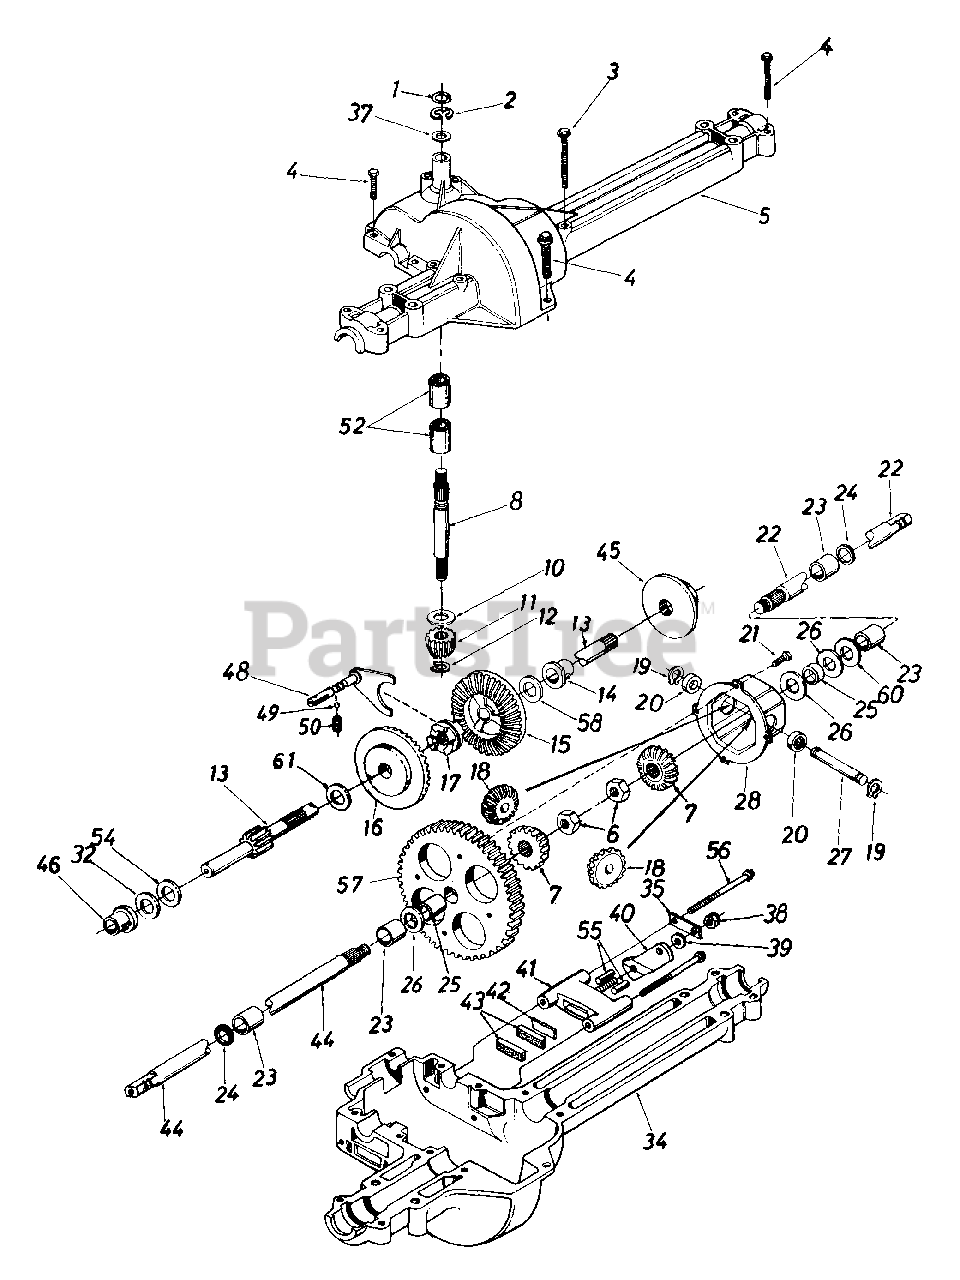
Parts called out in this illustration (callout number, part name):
3	Hex Wash. TT-Tap Scr. 1/4-20 x 1.75" Lg.
4	Hex Tap Scr. 1/4-20 x 1.25" Lg.
5	Upper Housing
6	Hex Jam Nut 1/2-20 Thd.
7	Miter Gear
10	Thrust Washer 5/8" I.D. x 1.25" O.D.
11	Pinion Input 14T
12	Retaining Ring
13	Drive Shaft - R.H. Brake
14	Flange Brg. 5/8" I.D. x 3/4" Lg.
15	Bevel Gear 42T Small I.D.
16	Bevel Gear 42T Large I.D.
17	Clutch Collar
18	Miter Gear 15T (H.D.)
19	Snap Ring
20	Thrust Bearing
21	Pan Head Scr. 1/4-20 x .50" Lg. w/Patch
23	Sleeve Bearing 3/4" I.D. x 1.0" Lg.
24	Oil Seal 3/4" I.D.
26	Fl-Wash..760" I.D. x 1.5" O.D.
28	Differential Can Ass'y.
32	Washer
34	Lower Housing
35	Anti-Rotation Brkt.
37	Washer
38	Hex Nut 5/16-24 Thd.
39	Fl-Wash..344" I.D. x .875" O.D.
40	Actuating Arm
41	Brake Yoke
42	Puck Plate
43	Brake Puck
46	Flange Bearing 5/8" I.D. x 15/16" Lg.
48	Shift Fork Ass'y.
49	Ball Detent .250" Dia.
50	Spring Detent
52	Needle Brg. 5/8" I.D. x 1/2" Lg.
54	Fl-Wash. 5/8" I.D. x 1" O.D. x .020 Thk.
55	Actuating Pin 5/16" Dia.
56	Hex Wash Hd. Self-Tap Scr. 1/4-20 Thd.
57	Differential Gear 58T
58	Fl-Wash. 5/8" I.D. x 1" O.D. x .020 Thk.
60	Washer
61	Thrust Washer
